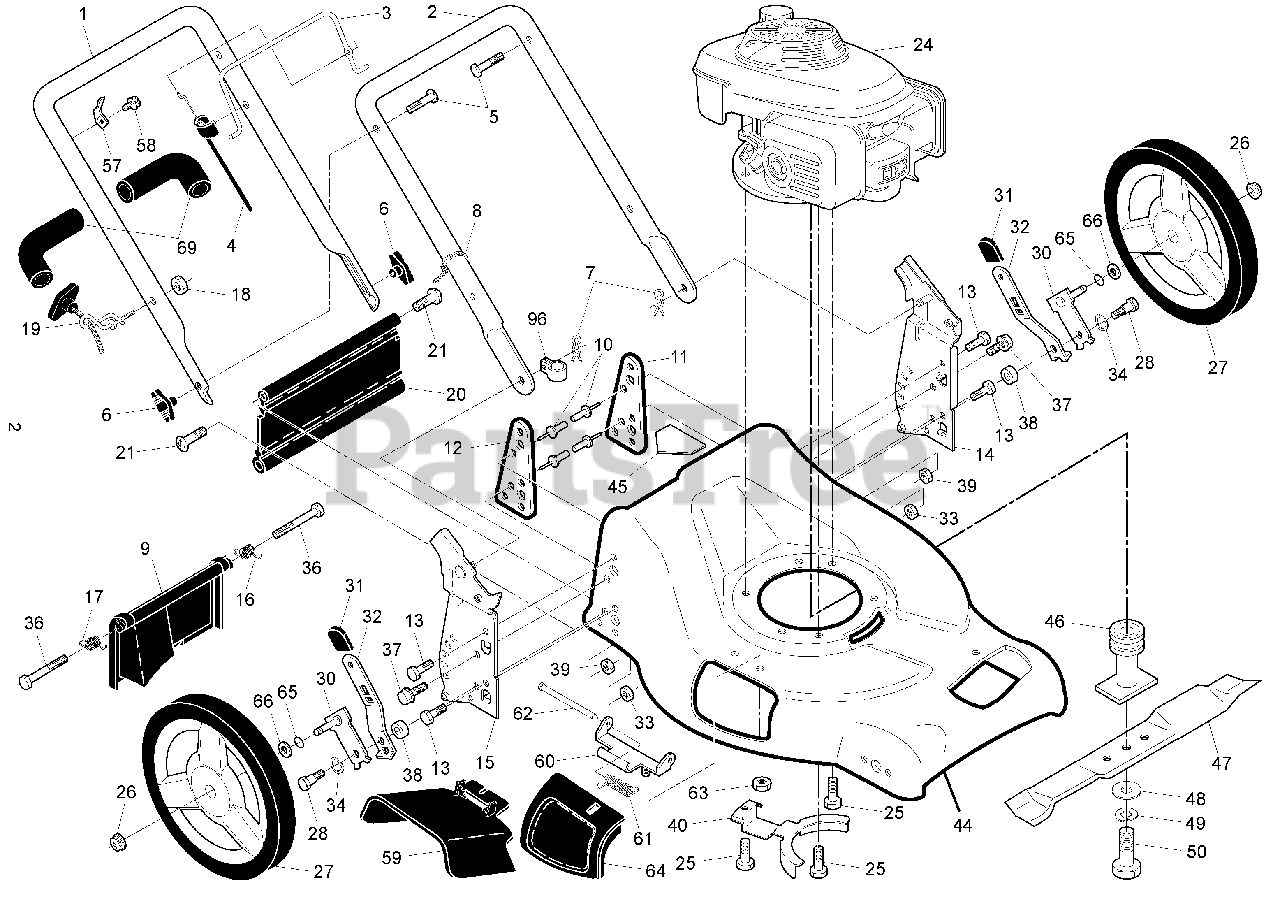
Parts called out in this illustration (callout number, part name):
1	Upper Handle
2	Lower Handle
3	Control Bar
4	Engine Zone Control Cable
5	Handle Bolt
6	Handle Knob
7	Hairpin Cotter
8	Wire Tie
9	Rear Door Assembly
11	Support Bracket, LH
12	Support Bracket, RH
13	Screw 1/4-20 x 5/8
14	Handle Bracket Assembly, LH
15	Handle Bracket Assembly, RH
16	Spring, Rear Door, LH
17	Spring, Rear Door, RH
18	Keps Locknut 1/4-20
19	Rope Guide
20	Rear Skirt
21	Screw, Hinge 1/4-20 x 1/2
25	Hex Head Thread Rolling Screw 3/8-16 x 1-1/8
26	Hex Flange Nut
27	Wheel & Tire Assembly, Rear, 12"
28	Shoulder Bolt 5/16-18 x .33
30	Axle Arm Assembly, Rear
31	Selector Knob
32	Selector Spring
33	Nut, Hex 5/16-18
34	Washer, Curved, Cyindrical
37	Thread Cutting Screw w/Sems 5/16-18 x 3/4
39	Nut, Hex, Flangelock 5/16-18
40	Belt Keeper
44	Kit, Lawn Mower Housing
45	Danger Decal
46	Blade Adapter / Pulley
47	Blade, 21"
48	Hardened Washer
49	Helical Washer
50	Hex Head Machine Screw 3/8-24 x 1-3/8 Grade 8
57	Upstop Bracket
59	Discharge Deflector
60	Hinge Bracket
63	Nut, Hex
64	Mulcher Door
66	Washer, Flat 1/2
69	Grip, Foam
96	Clip, Cable
